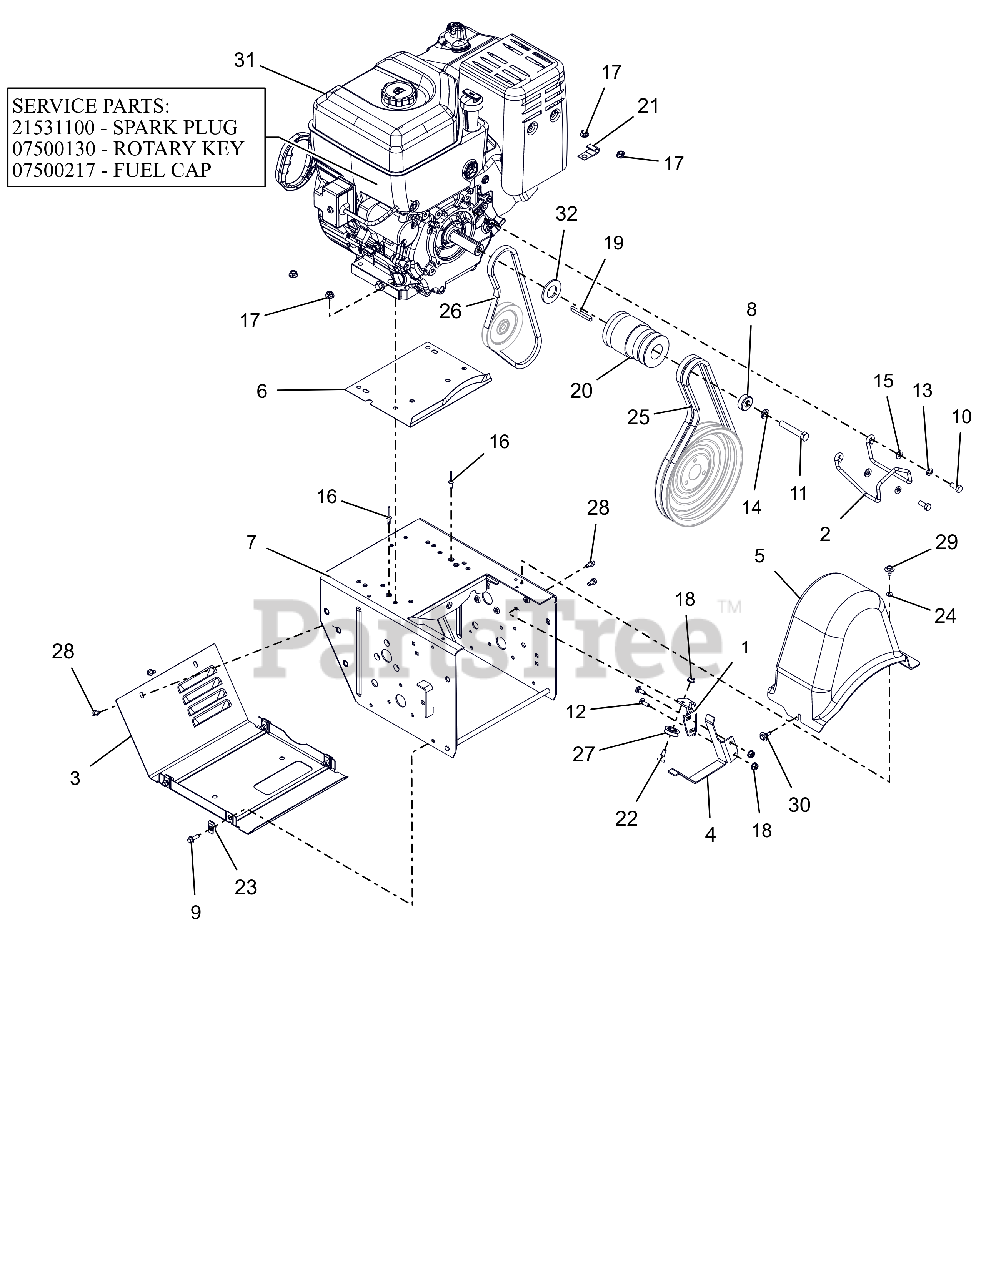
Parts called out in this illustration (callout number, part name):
1	BRACKET, CLUTCH CABLE
2	FINGER, BELT
3	COVER, BOTTOM - VENTILATED
4	FINGER, BELT - FLAT
5	COVER, BELT-LARGE
6	BAFFLE, WATER - LARGE BLOCK
7	FRAME, MAIN - PRO (WELDMENT)
8	BSHG-SPACER .47X1.25X.50
9	BLT-HEX .25-20X.75 HWH YZ GR5
10	BLT-HEX .31-24X.75 YWZC GR5
11	BLT-HEX .44-20X2.50 GR5 YWZC
12	@BLT-RDHDSQNK .25-20X.75 G5YZ
13	WSHR-LK .312X.097 HVY YWZC
14	@WSHR-LK .44X.109 REG YWZC
15	@WSHR-FL-STL.344X.688X.065YWZC
16	RVT-POP .187 YZ
17	@NUT-LK-CTR-FLG .31-18 YZ GR F
18	@NUT-LK-TOP-FLG .25-20 YWZC
19	KEY, SQ .248/.246 X 2.25
20	SHEAVE, COMBO HYDRO TRACK 4L
21	J-CLAMP
22	BOLT, SHLDR-.375X.375X.25-20
23	NUT-RTNR .25-20X.56
24	NUT-PUSH .25X.50 O.D.
25	V-BELT, HA-RAW EDGE (SET)
26	V-BELT, 4L-WRAPPED
27	PULLEY, CABLE
28	SCR-TAP .25-20X.50 HWH TR YWZ
29	SCR-TAP .25-20X.50 LGHWH TR YZ
30	SCR-TAP .25-20X.5 CAPTIVE
31	ENGINE, BRIGGS PF 2100, 120V
31	PLUG, SPARK 20HP B&S VANGUARD
31	KEY, IGNITION ROTARY B&S
31	CAP, FUEL - BRIGGS & STRATTON
32	WSHR-FL-STL- 1.062X2.0X.134 YZ
